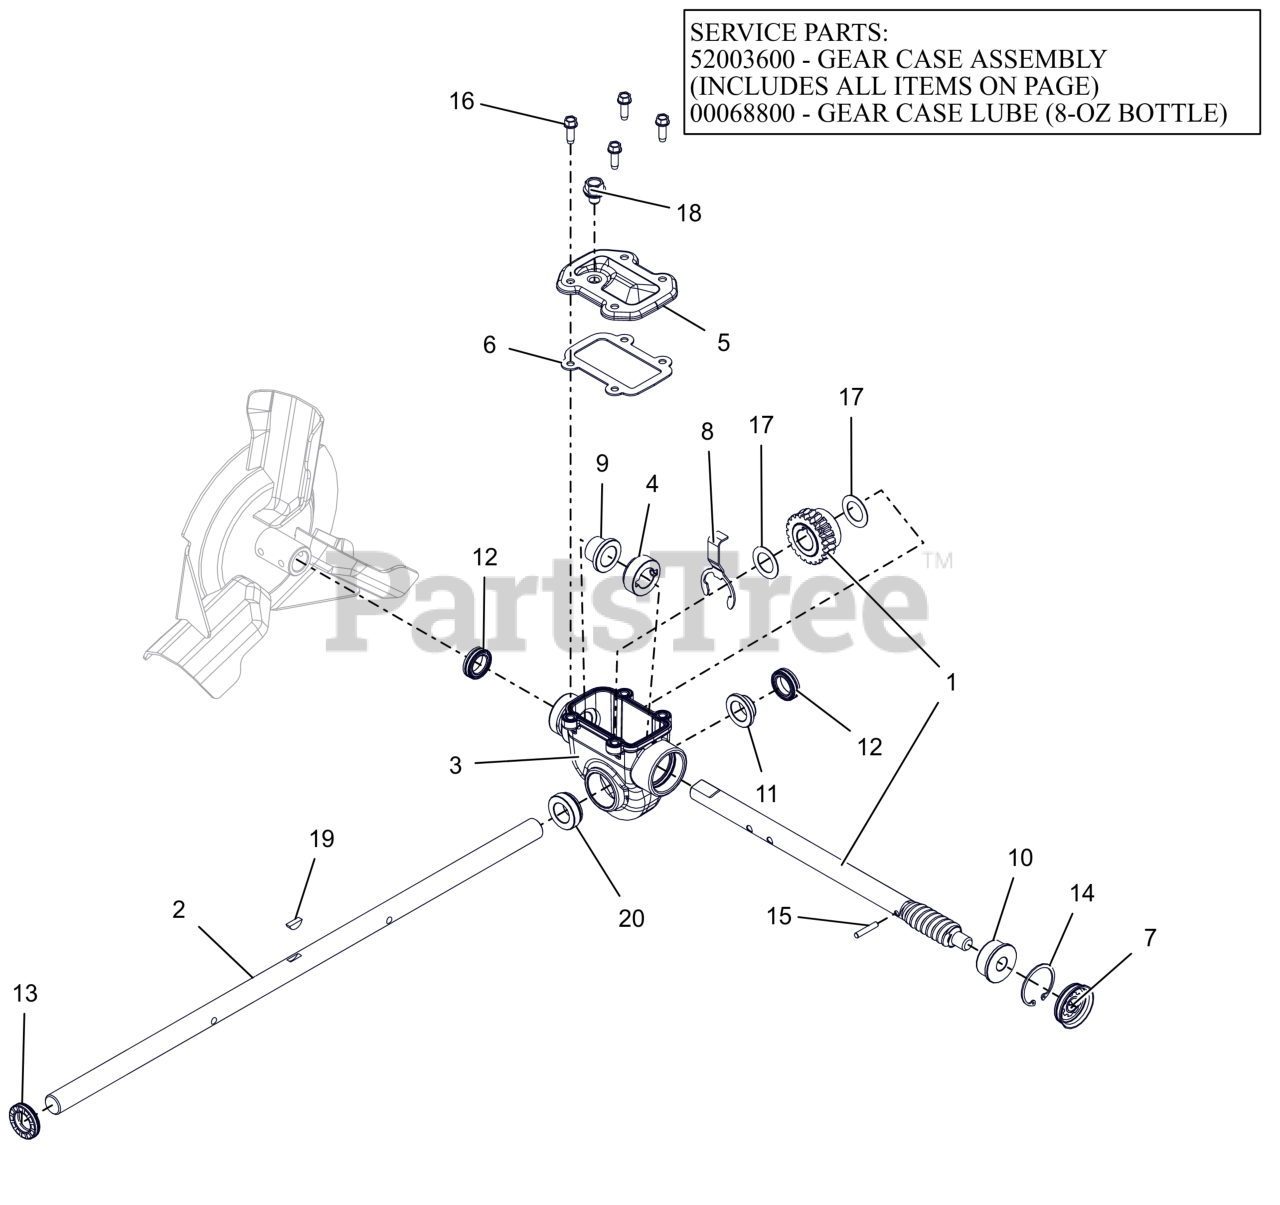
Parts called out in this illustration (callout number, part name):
1	SHAFT AND WORM GEAR ASSEMBLY
2	SHAFT, RAKE - 24" (.750 DIA)
3	GEARCASE, COMPACT ALUMINUM
3	GEAR CASE, 24" ALUM SM TOP-LD
3	ARIENS L3 LUBE, 8 OZ BOTTLE
4	THRUST COLLAR, .75" ID SLIPFIT
5	COVER, TOP - COMPACT
6	GASKET, TOP - COMPACT GEARCASE
7	COVER, GEAR CASE 1.50"
8	BUSHING RETAINER, COMPACT
9	BSHG-FLG .755X.878X.75X1.25
10	BSHG-FLG .503X1.303X.62X1.465
11	BSHG-FLG .755X.878X.424X1.25
12	SEAL-OIL .748X1.125X.312 TBC29
13	SEAL-OIL .748X1.300X.250 TBC29
14	RG-RTNG-INT 1.500X.050
15	PIN-STR .188X1.00 6150
16	SCR,TAP .25-20X.75 HWH TR ZCC
17	WSHR, FLT .760X1.225X.032 ZCC
18	SCR, .380-15X.500 W/SEAL WASHER
19	KEY-WDRF .19X.63 HRD #61
20	BSHG-FLG COMPACT, RIGHT
